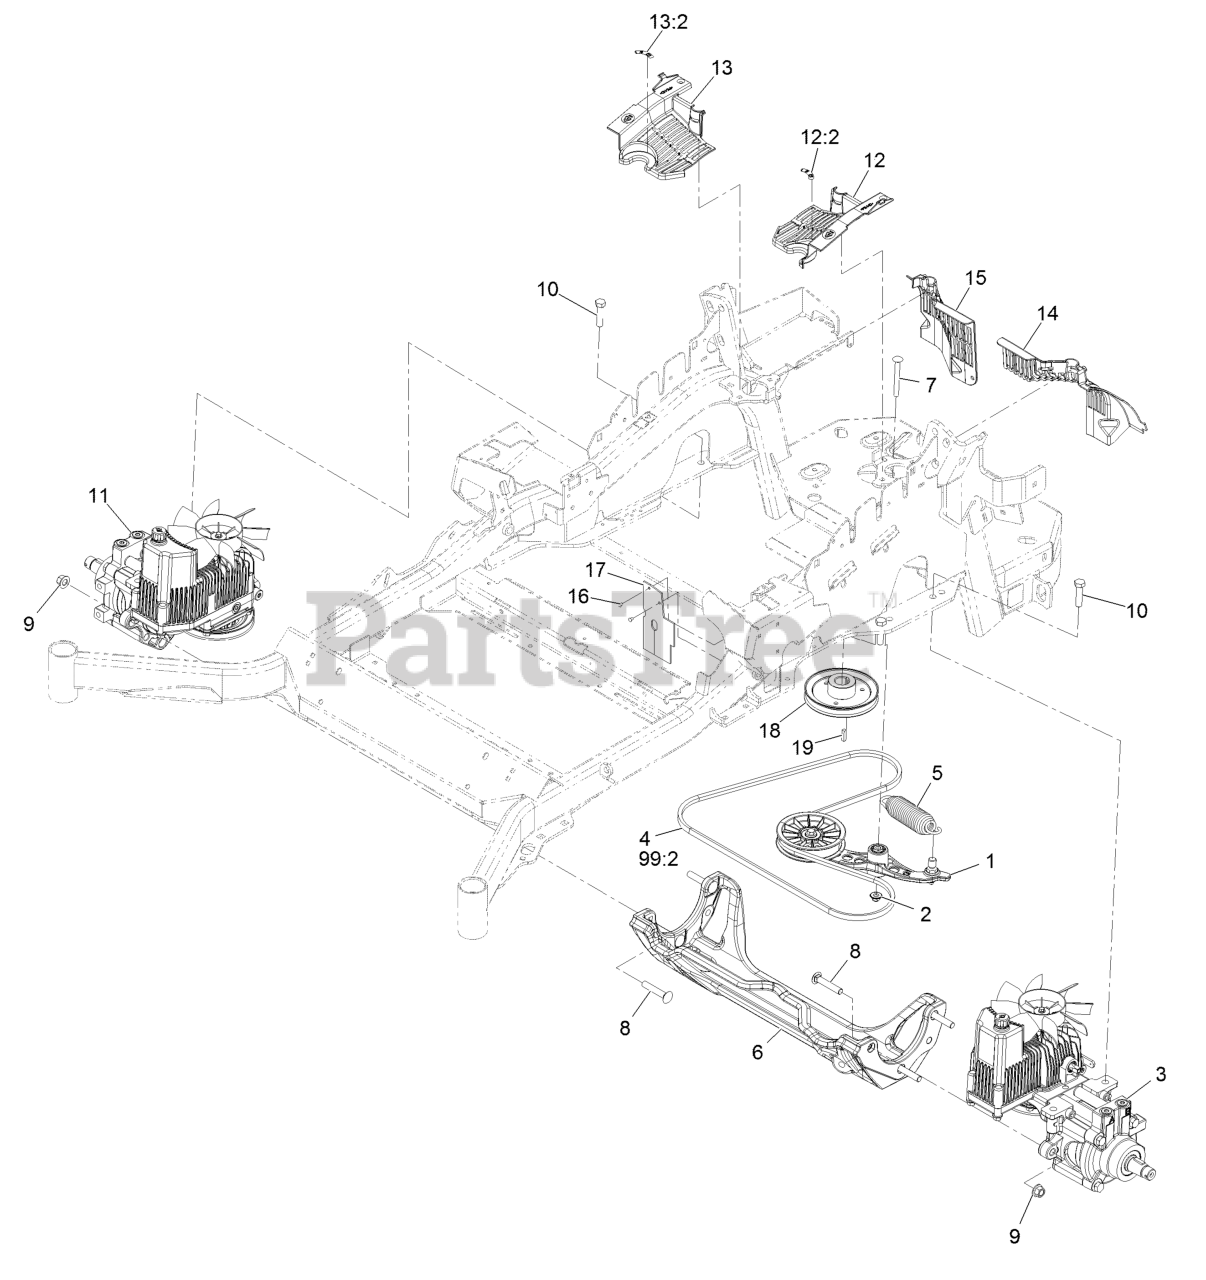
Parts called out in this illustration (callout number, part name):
1	Pump Idler ASM
2	Nut-Nyloc 3/8-16 Flg
3	LH Hydro ASM (16Cc W/ Shock)
4	Belt
5	Spring-Extension
6	Cradle-Hydro
7	Bolt-Carriage Shoulder 3/8-16 X 3 1/2
8	Screw-CARR
9	Nut-Lock 1/2-13
10	Screw-HH 1/2-13 X 1 1/4
11	RH Hydro ASM (16Cc W/ Shock)
12	LH Hydro Guard ASM
12:2	Decal-Oil, Hydro
13	RH Hydro Guard ASM
13:2	Decal-Oil, Hydro
14	Guard-Hydro Rear, LH Trim
15	Guard-Hydro, Rear (RH)
16	Rivet 3/16 X 1/4
17	Deflector-Air Flow
18	Sheave
19	Key-Machine 1/4 X 1/4 X 1
99	Bottle-Oil, 32Oz Hydraulic
99	Filter-Hydro
99	Bottle,Oil 1 Gallon Hydraulic
99	Kit, Hydro Service
99:1	Bottle-Oil, 32Oz Hydraulic
99:2	Belt
99:3	Filter-Hydro
